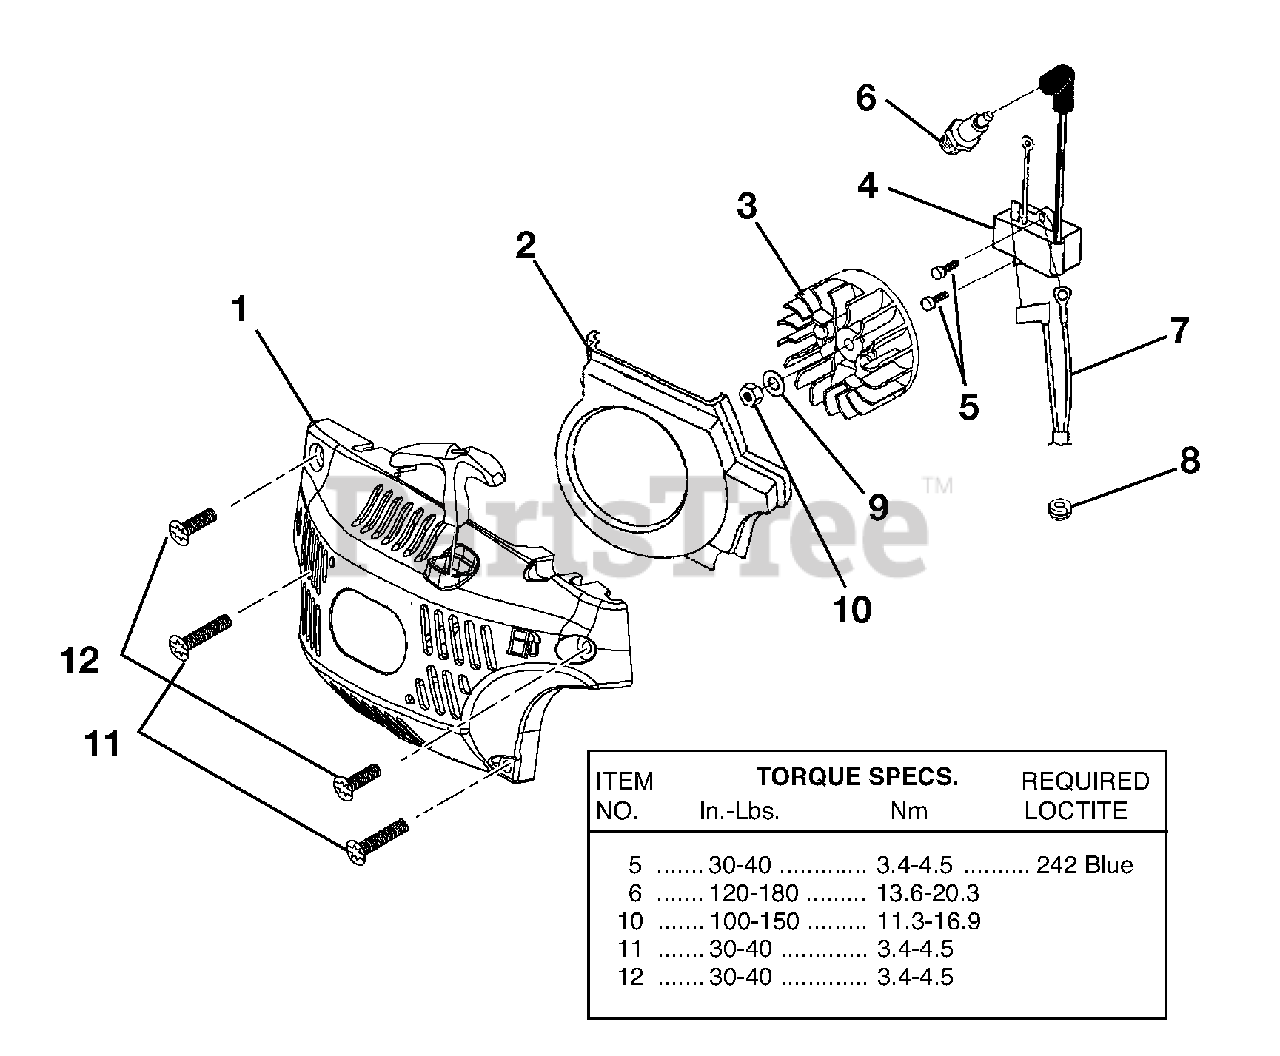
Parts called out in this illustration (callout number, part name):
1	Starter Cover Assembly
2	Baffle, Fan Housing
3	Rotor & Starter Pawl
4	Ignition Kit
5	Screw, Thread Form (8-32 x 5/8")
6	Spark Plug
7	Ignition Switch Harness
8	Grommet, Wire Harness (Split)
9	Washer, Flat
11	Screw, Truss Hd., Plastite (10-14 x 7/8")
12	Screw, Truss Hd., Plastite (10-14 x 5/8")
